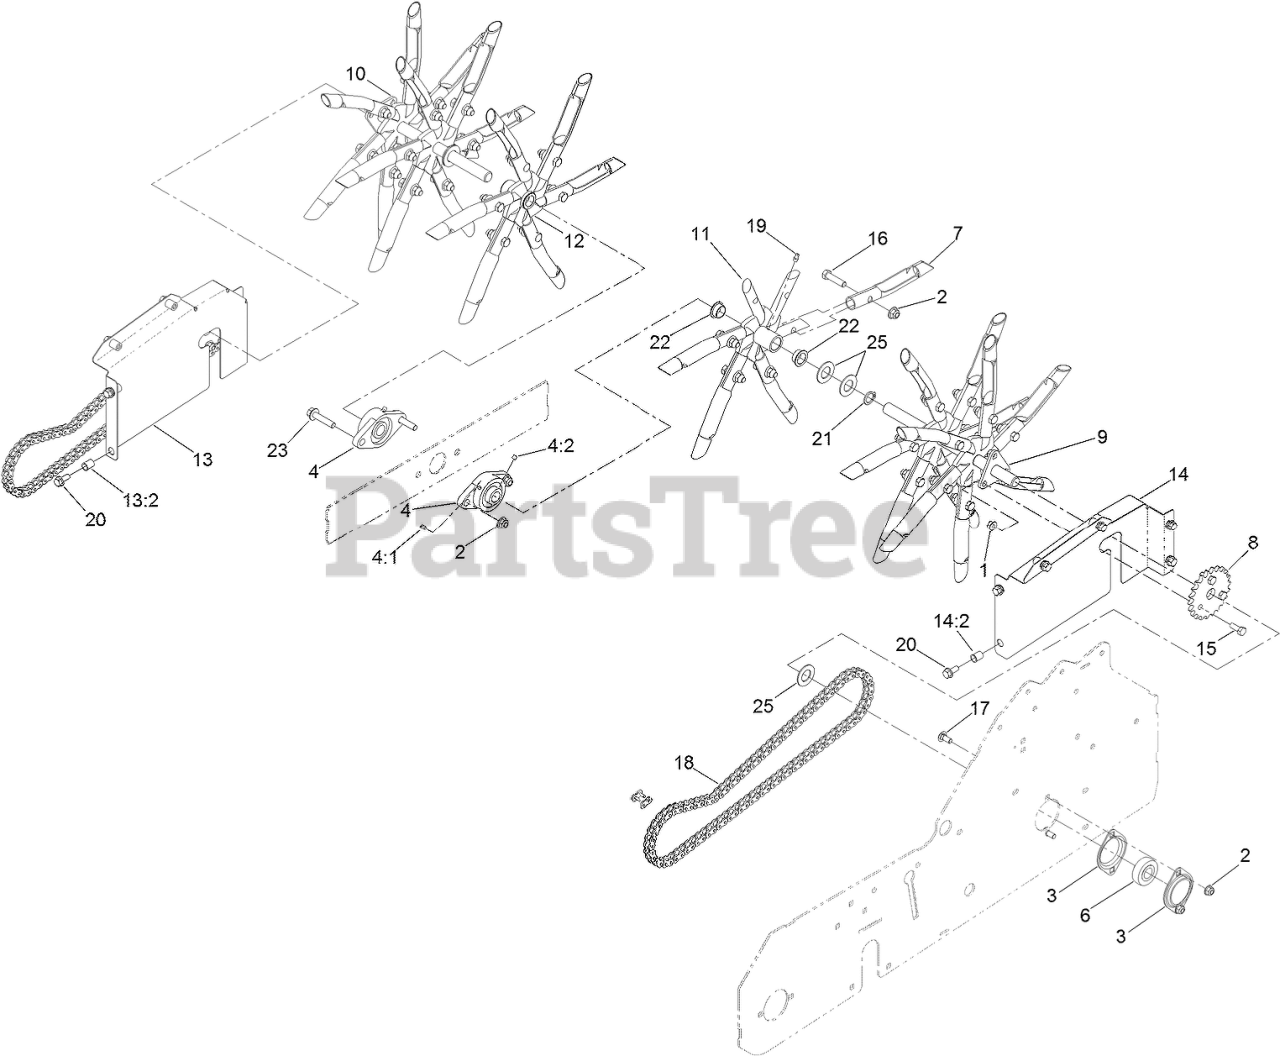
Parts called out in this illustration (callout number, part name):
1	NUT-HF, NI
2	NUT-HF, NI
3	FLANGE-BEARING
4	BEARING-FLANGE
4:1	FITTING-STRAIGHT
4:2	SCREW-SET, HSH
6	BEARING-LOCK, COLLAR
7	TINE-CORING (3/4 INCH)
8	SPROCKET-#40 22T
9	WHEEL-TINE, LH
10	WHEEL-TINE, RH
11	Spyder Tine Wa
12	TINE-SPYDER
13	RH CHAIN GUARD ASM
13:2	NUT-CLINCH
14	LH CHAIN GUARD ASM
14:2	NUT-CLINCH
15	SCREW-HH
16	SCREW-HH
17	BOLT-CARR
18	CHAIN-DRIVE
19	FITTING-GREASE
20	SCREW-HHF
21	RING-RETAINING
22	BUSHING-BRONZE
23	SCREW-HHF
